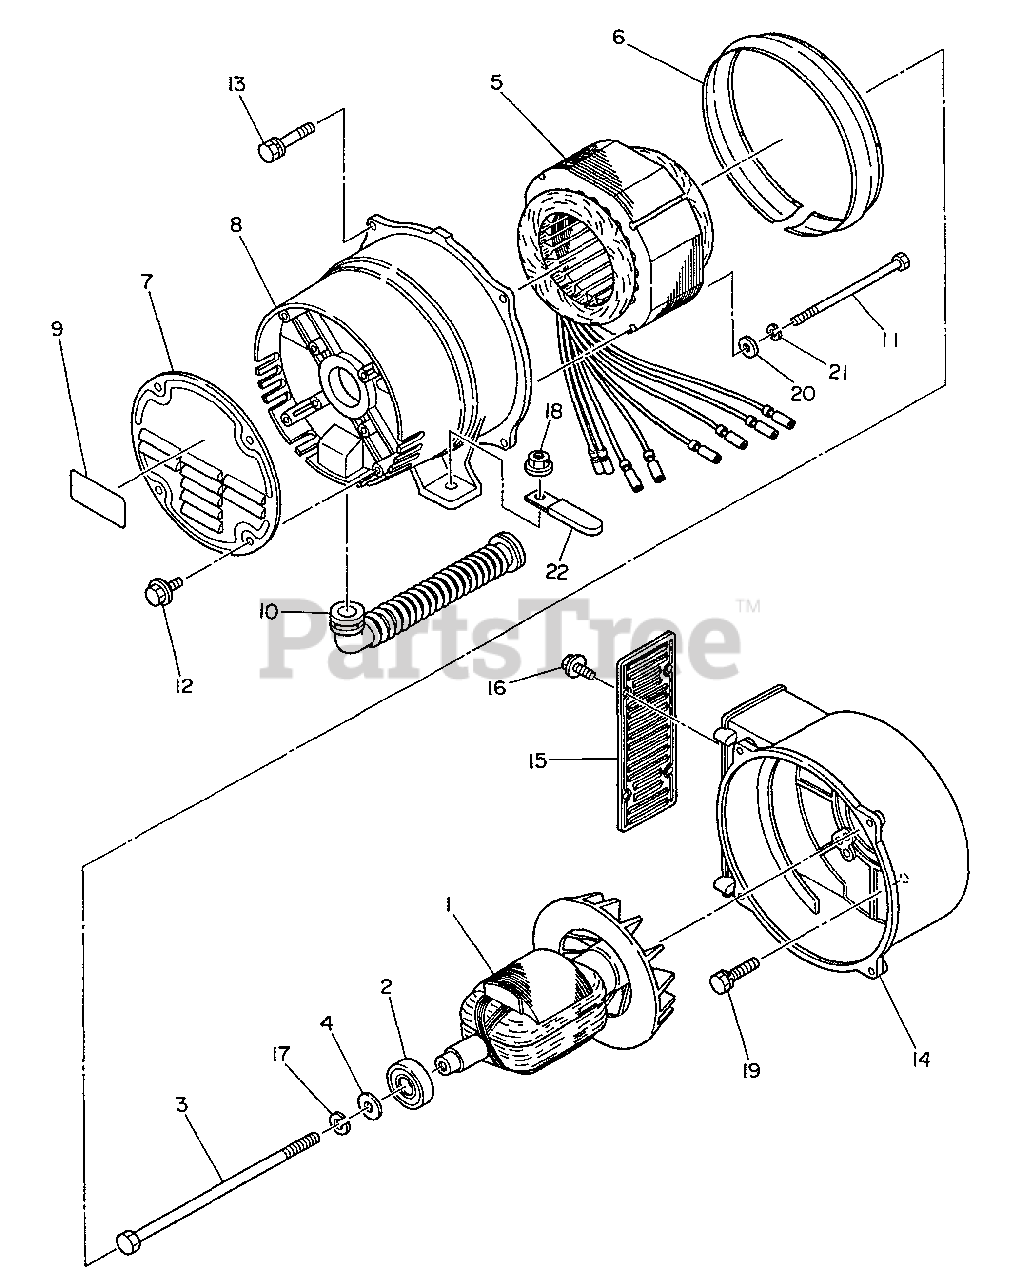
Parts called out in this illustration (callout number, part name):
1	FLYWHEEL ASSY
2	BEARING, BALL 6205RS
3	THROUGH BOLT
4	WASHER
5	STATOR ASSY
6	SUPPORT RING
7	END COVER
8	REAR COVER
9	LABEL - DANGER
10	BUSHING
11	BOLT
12	BOLT, FLANGE
13	BOLT
14	FRONT COVER
15	FRONT PROTECTOR
16	SCREW - TAPPING
17	LOCKWASHER
18	NUT, FLANGE
19	BOLT
20	WASHER
21	LOCKWASHER
22	CLAMP
